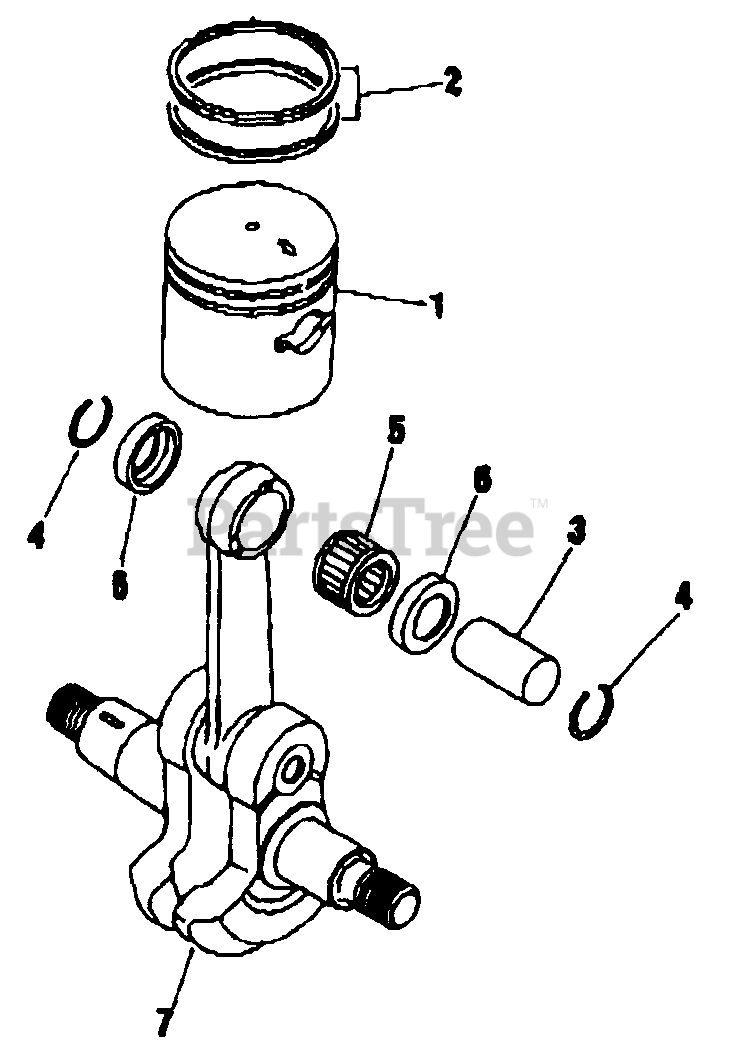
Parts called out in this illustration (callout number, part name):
1	PISTON
2	RING, PISTON
3	PIN, PISTON
4	RING, RETAINING
5	BEARING, NEEDLE
6	WASHER, THRUST
7	CRANKSHAFT ASSY
